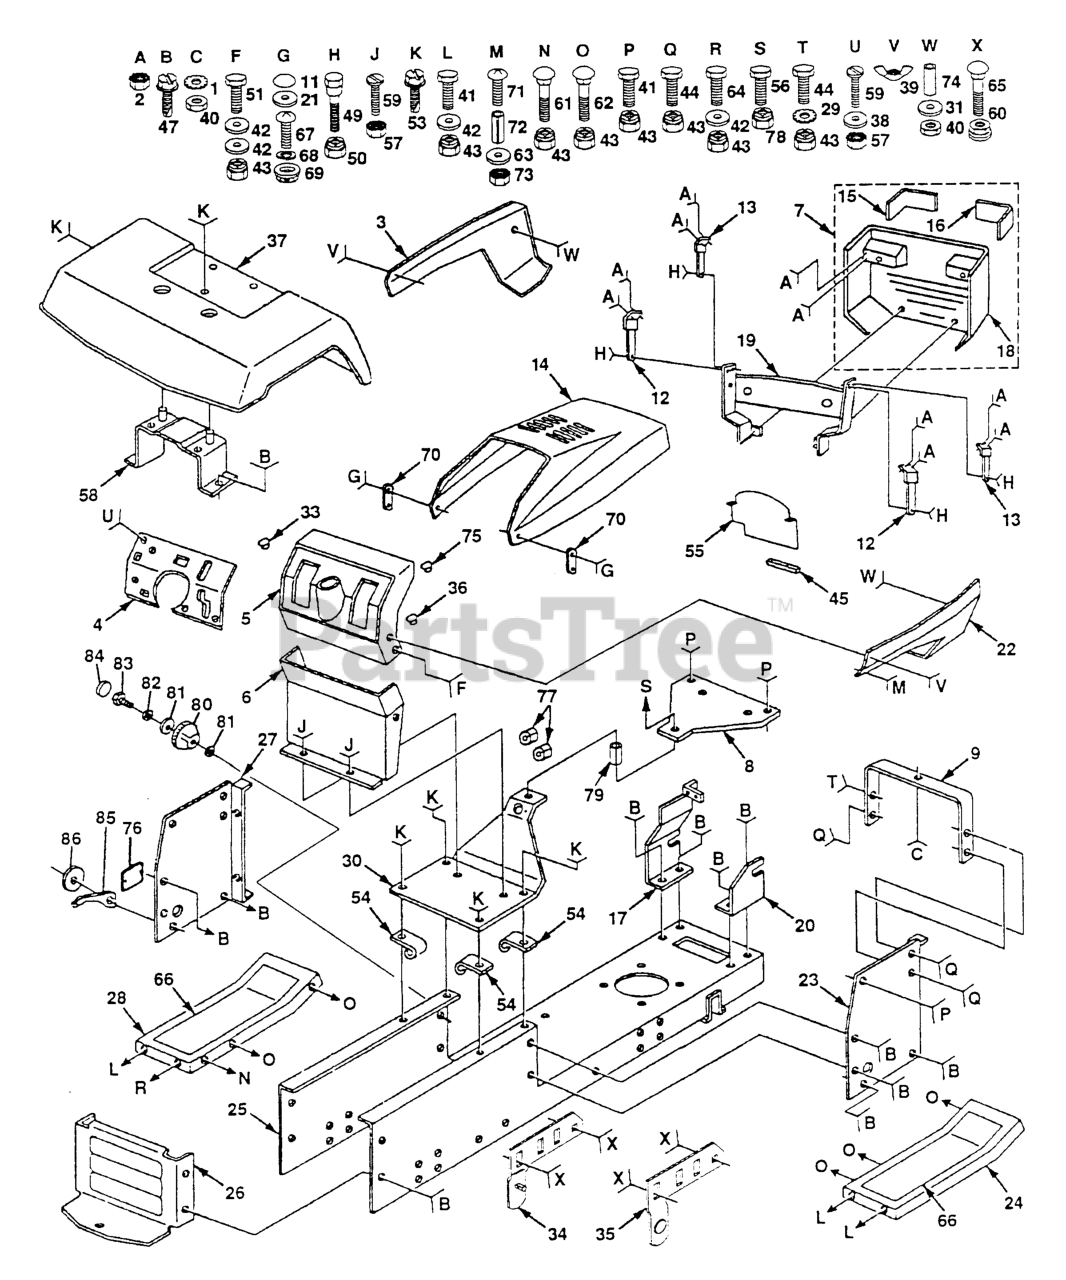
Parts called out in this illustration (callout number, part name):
1	Washer, Lock, External Tooth 1/4
2	NUT
3	PANEL SIDE LH
5	DASHBOARD
6	DASH ASSY LT NLA
7	GRILL
8	PLATE, SUPPORT
9	SUPPORT ASS'Y
11	SNAP CAP LT
12	STRAP ASSY LT
13	STRAP ASSY LT
14	HOOD.HUSQVARNA.ORANGE
15	LENS LH
16	LENS RH
17	SUPPORT RH YTH
18	GRILL
19	SUPT, ASS'Y GRILL
20	SUPPORT LH YTH
22	PANEL SIDE RH
23	PANEL DASH RH
24	PAD,SPACER
25	CHASSIS ASM
26	DRAWBAR
27	PANEL DASH LH
28	ROLL PIN NLA
29	LOCKWASHER
31	WASHER PM
33	PLUG BUTTON T
34	PIVOT BRACKET LH
35	PIVOT BACKET RH
37	FENDER
38	WASHER
39	WING NUT
40	NUT
42	WASHER
44	BOLT
45	FOAM-STRIP LT
47	SCREW
49	BOLT T
50	NUT.CROWNLOCK.1/4
51	BOLT
53	SCREW LT
54	CLIP T
55	BAFFLE,VERTICAL NLA
56	Bolt, Hex, Fin. 5/16-18 UNC x 2
57	NUT
58	BRACKET FENDER
59	Screw, Machine 5/16-18 UNC x 3/4
60	NUT
61	BOLT D
62	BOLT
64	BOLT
65	BOLT D
66	PAD FOOTREST T
67	SCREW
68	LOCKWASHER #10
69	WELDNUT
70	LATCH.HOOD.
71	RP SCREW
73	NUT **
74	SPACER NLA
75	PLUG-DASH T
76	COVER ACCESS
77	SNAP BUSHING T
80	HEIGHT INDICATOR
82	WASHER.LOCK.HVY.HLCL.SPR.5/16
83	BOLT.FIN.HEX.5/16-18UNC X 1.00
85	POINTER HGT
